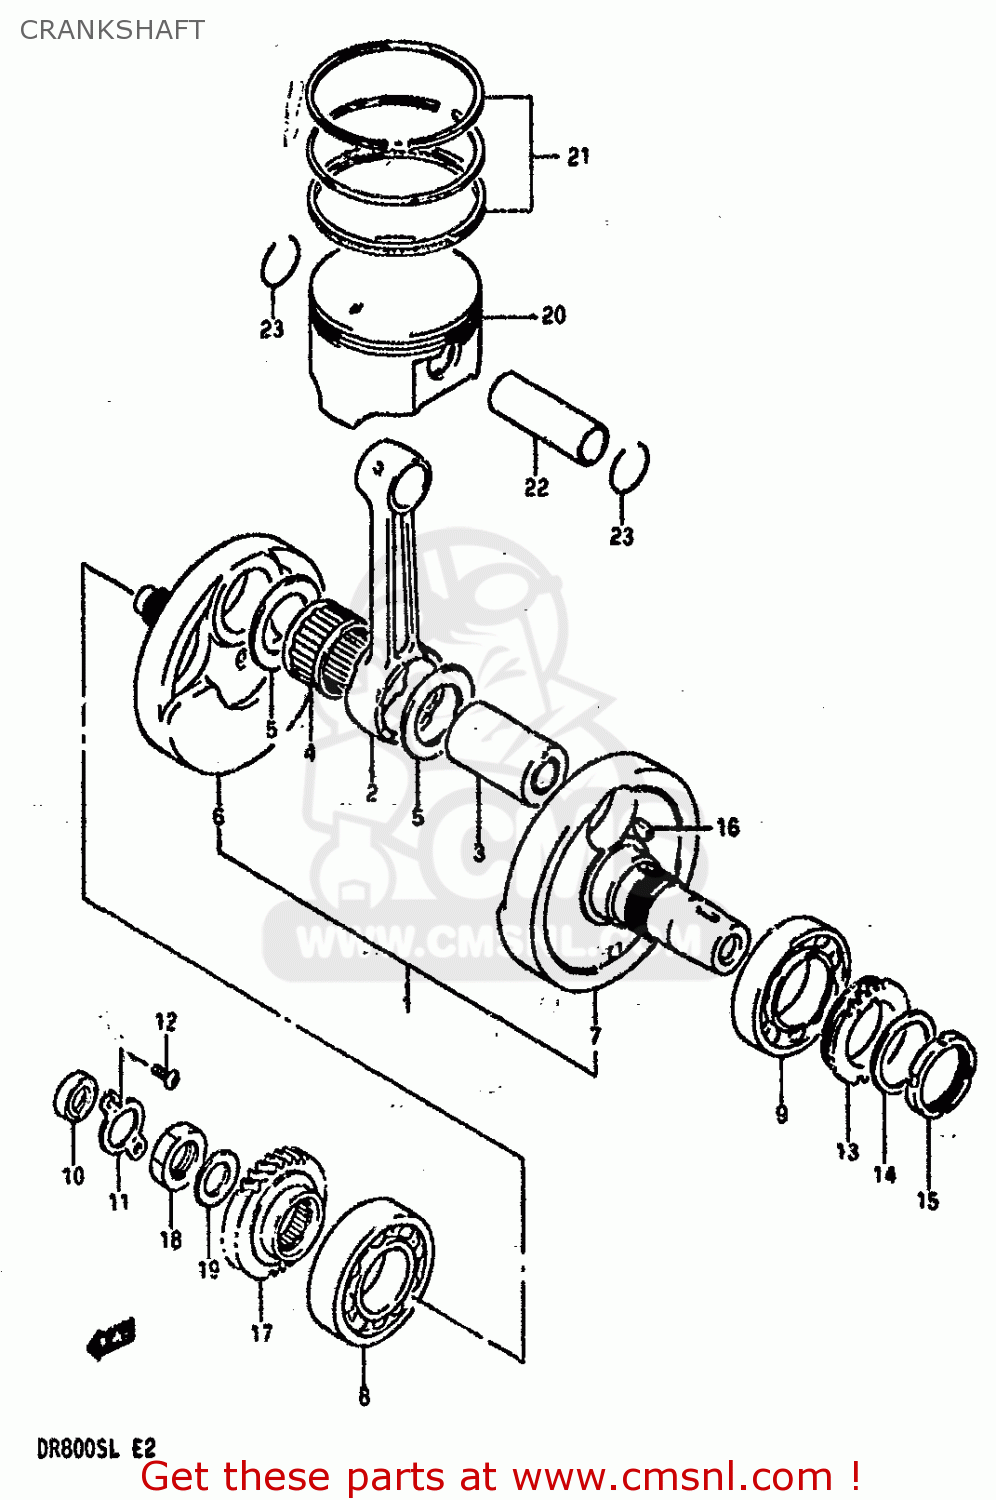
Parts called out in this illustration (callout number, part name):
1	CRANKSHAFT ASSY
2	ROD,CONNECTING
3	PIN,CRANK
4	BEARING
5	WASHER(41X61X1)
6	CRANKSHAFT, RH
7	CRANKSHAFT, LH
8	BEARING(40X90X23)
9	BEARING(45X85X19)
10	SEAL,OIL(16X30X6)
11	RETAINER,CRANKSHAFT BEARING,R
12	SCREW
13	SPROCKET,BAL.D
14	WASHER
15	NUT,BAL DRIVE SPRKT
16	KEY
17	GEAR, PRIMARY DRIVE (NT:33)
18	NUT
19	WASHER
20	PISTON
21	RING SET,PISTON
22	PIN,PISTON
23	CIRCLIP
